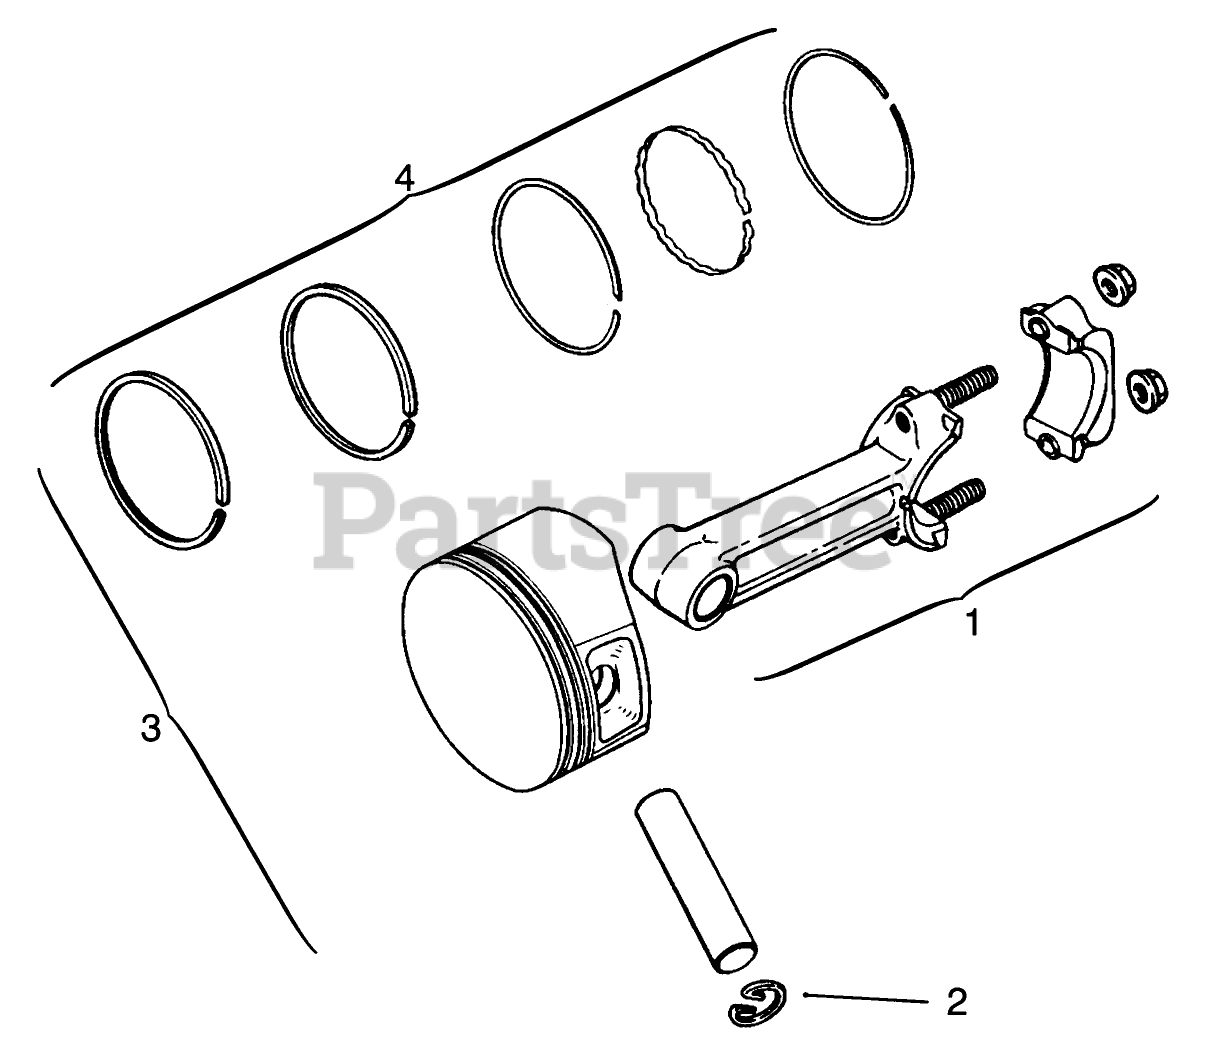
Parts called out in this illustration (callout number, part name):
1	Rod-Connecting Std.
2	Retainer, Pin
3	Piston & Ring Set Std.
4	Ring Set Std. & .003"
